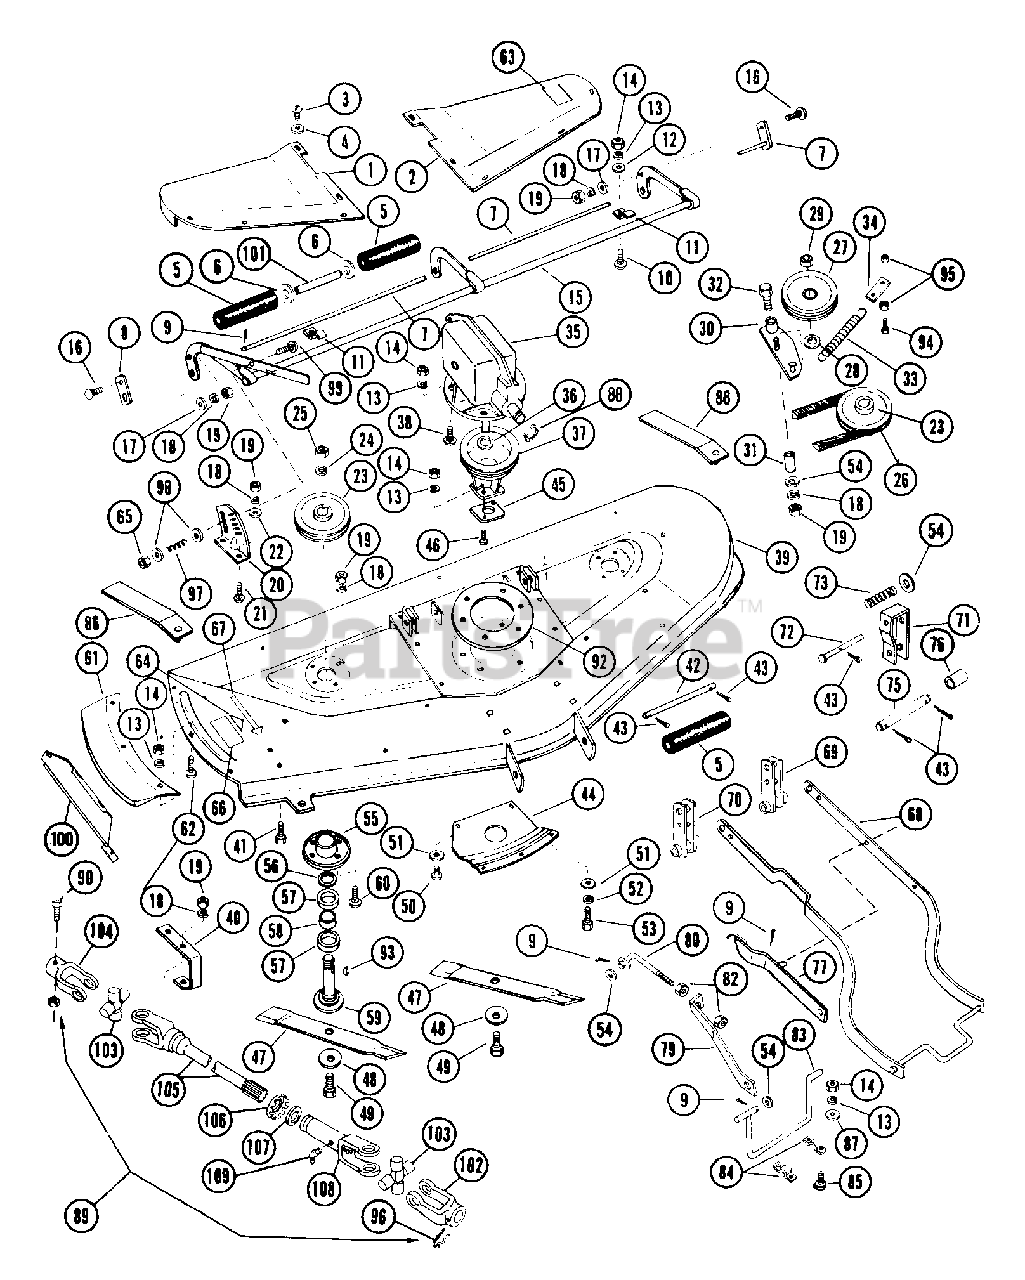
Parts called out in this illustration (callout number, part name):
1	R.H. SHIELD
2	SHIELD ASSEMBLY
3	SCR-TAP .250-20X.50 HH F
4	WSHR-FL-STL.281X.62X.065 PL
6	WSHR-FL-STL .688X1.750X.134
7	ROLLER SHAFT
9	PIN-COTR .18X1.0 PL
10	BLT-RDHDSQNK .31-18X1.00 PL
12	WSHR-FL-STL.344X.688X.065PL
13	WSHR-LK .312X.097 PL HVY
14	NUT-HEX .312-18
15	ROLLER ADJUSTMENT
16	BLT-RDHDSQSHNK .38-16X1.00 PL
17	WSHR-FL-STL .438X1.0X.083 PL
18	WSHR-LK .375X.094 MED PL
19	NUT-HEX .375-16
20	HEIGHT QUADRANT
21	BLT-RDHDSQNK .38-16X1.0 PL
22	WSHR-FL-STL .406X.812X.063 PL
23	PLY-? 4.50X.75
24	WSHR-LK-INT .750X.050 MED
25	NUT-JAM .75-16 PL
26	V-BELT, HA-WRAPPED
27	IDLER-FLAT 4.25 X .50 SAL&CLK
28	WSHR-FL-STL .531X.938X.104 PL
29	NUT-LK .50-13 PL
30	IDLER ARM
31	SPACER .394X.500X1.710
32	BLT-HEX .38-16X2.50 PL GR2
33	SG-TENS .105X.812X3.88 WLD 15
35	GEAR BOX ASSEMBLY-48IN DECK
36	WSHR-FL-STL .781X1.500X.060
38	BLT-RDHDSQNK .31-18X.75 SHT PL
39	DECK ASSEMBLY
40	R.H. SKID
41	BLT-RDHDSQNK .38-16X.75 SHT PL
43	PIN-COTR .12X1.0 PL
46	SCR-MCH .31-18X1.00 SLFL PL
48	BELLEVILLE WASHER
49	BLT-HEX .44-20X1.00 GR5
50	SCR-TAP .250-20X.50 HH F
51	WSHR-FL-STL.281X.62X.065 PL
52	WSHR-LK .250X.077 HVY PL
53	BLT-HEX .25-20X.50 PL GR2
54	WSHR-FL-STL .531X1.062X.095 PL
55	FLANGED BEARING HOUSING
56	WSHR-FL-STL .755X1.375X.062 PL
57	BRG-BALL .750X1.781X.61
58	SPACER .807X1.001X.445
59	SPINDLE SHAFT
60	BLT-RDHDSQNK .375-16X.75 PL
61	CHUTE EXTENSION
62	SCR-MCH .31-18X.62 SLTR PL
63	DECAL CAUTION
64	SAFETY LABEL
65	NUT-LK .312-18 PL
66	DECAL ROTATING PARTS
67	DECAL CUTTING WIDTH
68	MOWER HANGER
71	SUPPORT CHANNEL
72	PIN-CLEV .498X4.50 YWZC
73	SG-COMP .62X.68X1.75
75	PIN-CLEV .498X4.31 YWZC
76	SPACER .516X.749X.938
80	ADJUSTING ROD
82	NUT .50-13 PL
83	SUPPORT SHAFT
85	BLT-RDHDSQNK .31-18X.75 GR5 PL
86	RAMP
87	WSHR-FL-STL.344X.688X.065PL
88	RG-RTNG-EXT .750X.078
89	P.T.O. SHAFT ASSEMBLY
90	SHEARBOLT & NUT ASSEMBLY
93	KEY-WDRF .188X.75X.313 SAE 9
94	BLT-HEX .38-16X1.00 PL
95	NUT-JAM .375-16 PL
96	PIN-HAIR INT .18X1.18X3.25 PL
97	SG-COMP .063X.53X1.187
98	WSHR-FL-STL .38X.875X.083 PL
99	BLT-RDHDSQNK .31-18X1.75 PL
100	LEAF MULCHER 48 IN - GT
101	SPACER .726X.875X6.375
103	JOURNAL CROSS & BEARING ASSEMB
105	YOKE & SHAFT
106	RETAINER CAP
107	GREASE SEAL
109	SPIN DRIVE ZERK FITTING
